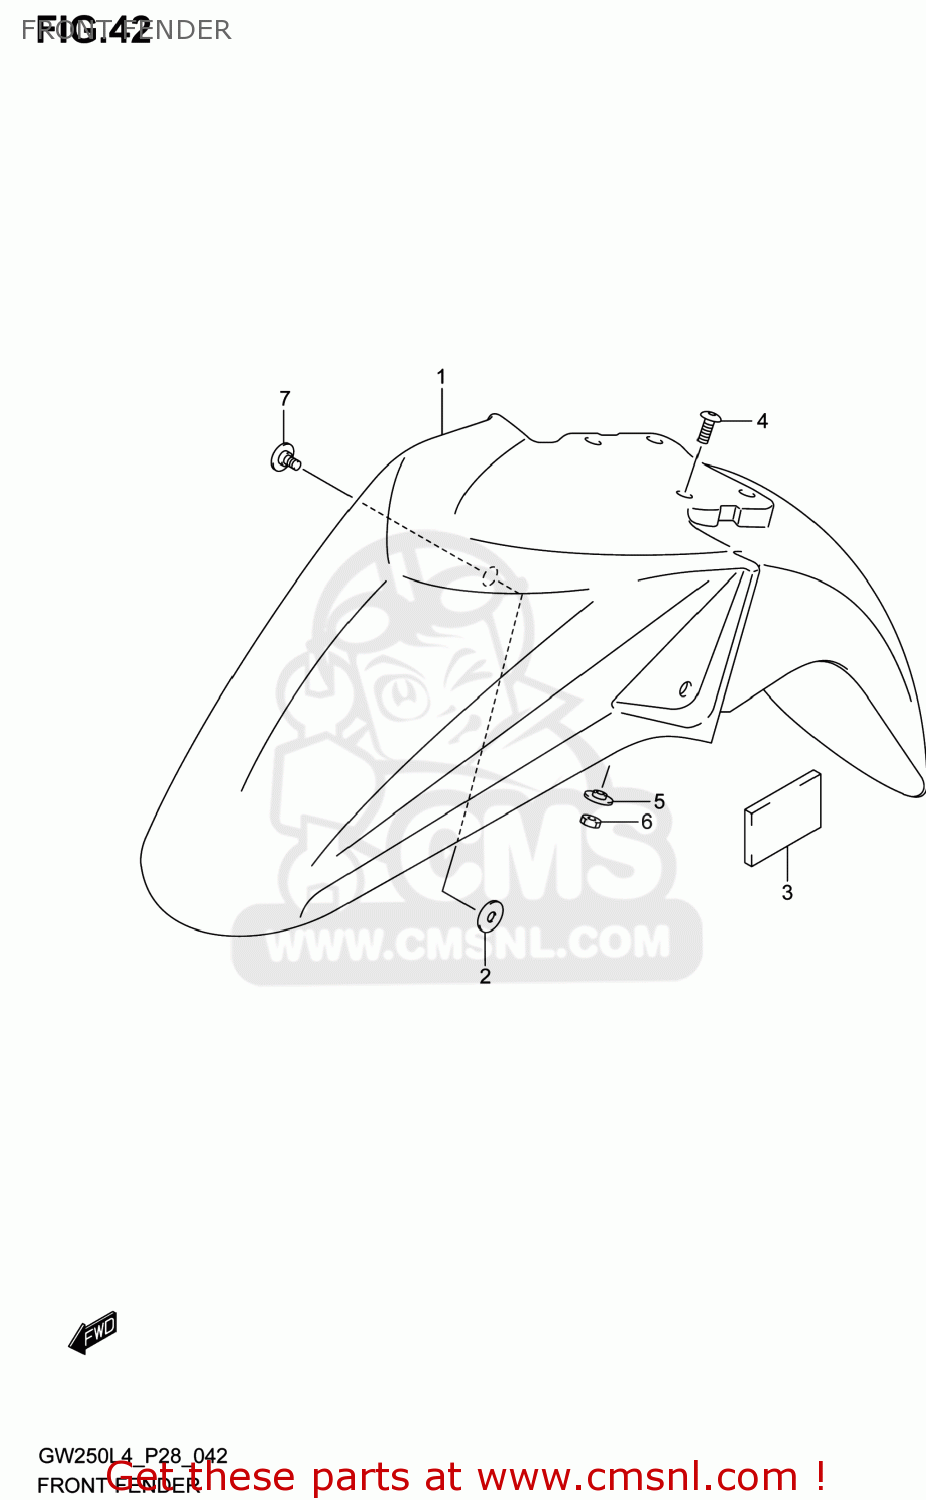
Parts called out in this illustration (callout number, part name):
1	FENDER,FR
2	WASHER,PLANE
3	CUSHION,FR FENDER
4	SCREW(6X16)
5	WASHER
6	NUT
7	SCREW,FR FENDER FR
